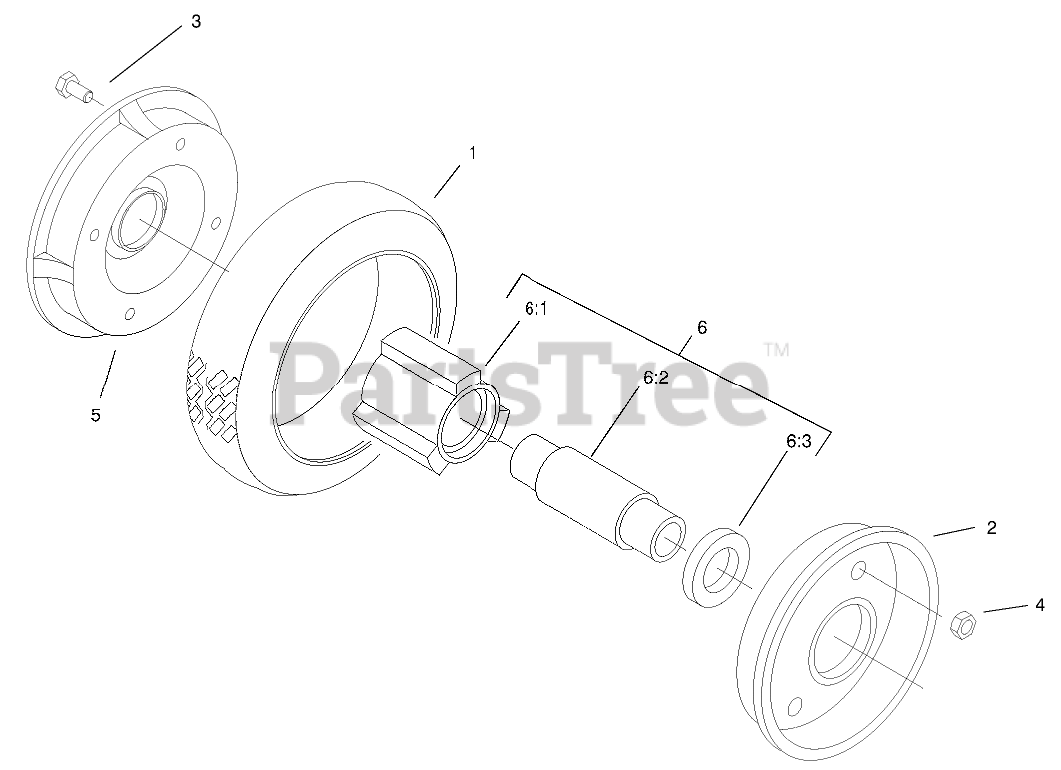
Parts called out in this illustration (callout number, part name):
2	PLATE-WHEEL, HALF
3	SCREW-HH
4	NUT-LOCK, NI
5	WHEEL HALF AND GEAR ASM
6	Hub and Bearing ASM
6:1	HUB-BEARING
6:2	SPACER-BEARING
6:3	BEARING-WHEEL
